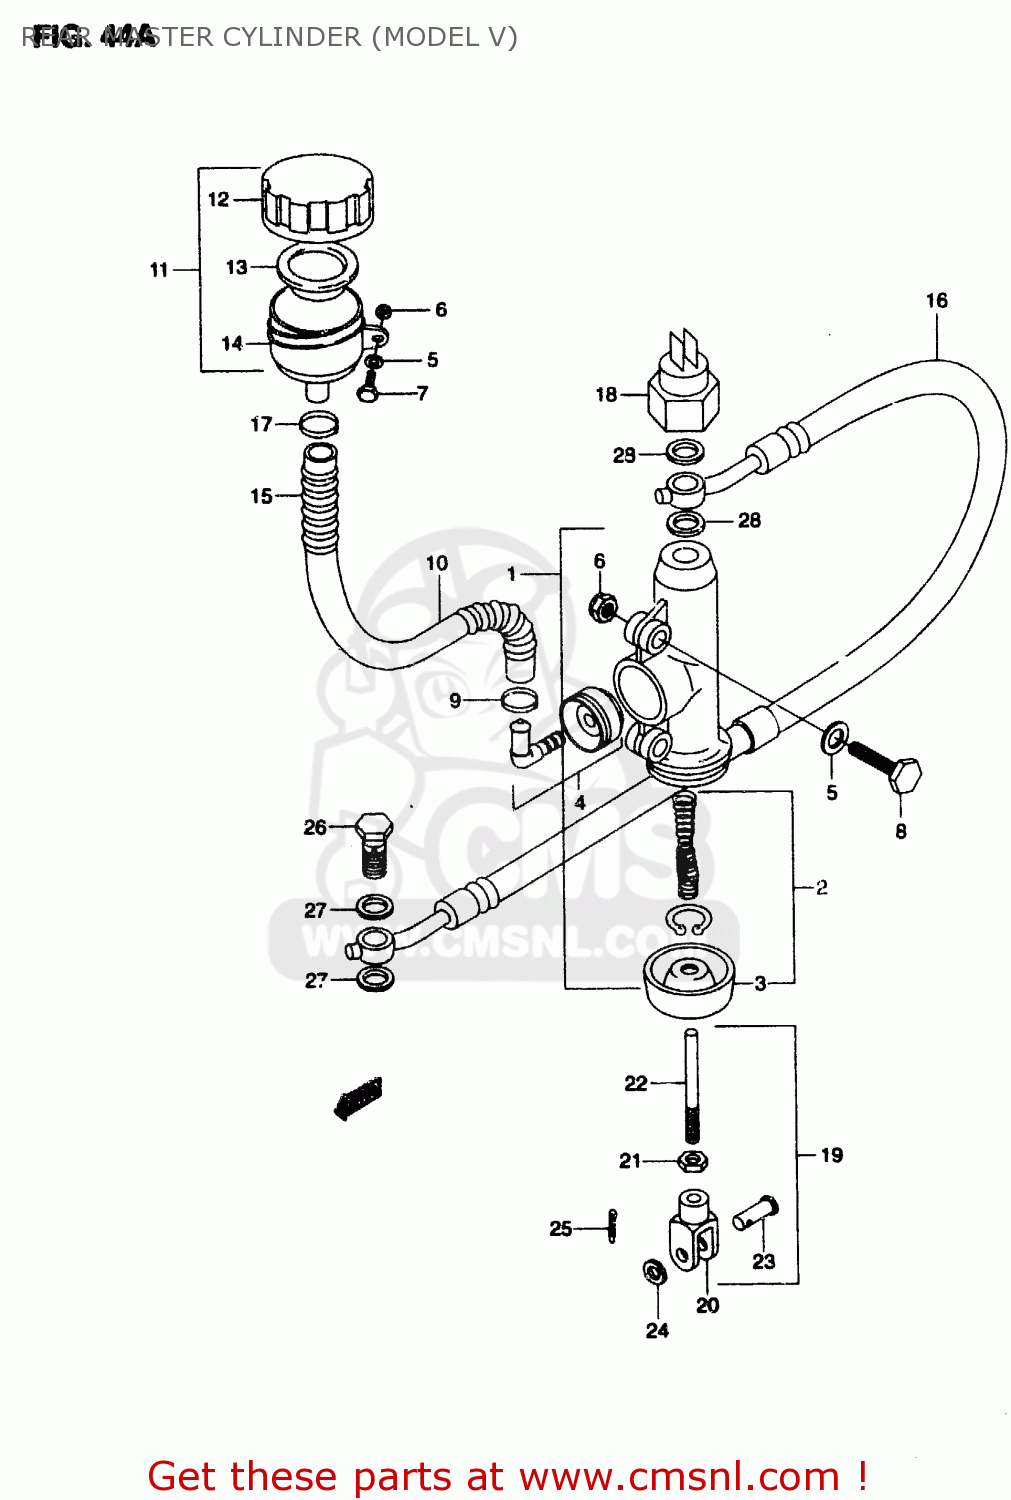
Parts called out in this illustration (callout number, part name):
1	CILINDER ASSY
2	PISTON CUP SET
3	YOKE
4	CONNECTOR
5	WASHER
6	NUT
7	BOLT
8	BOLT
9	CLIP
10	HOSE (L:220)
11	TANK ASSY, REAR RESERVOIR
12	CAP
13	DIAPHRAGM
14	TANK
15	SPRING
16	HOSE, REAR BRAKE
17	CLAMP
18	CONTACT
19	PLATE ASSY
20	YOKE
21	NUT 6MM
22	ROD, PUSH
23	PIN
24	WASHER
25	PIN
26	BOLT
27	WASHER
